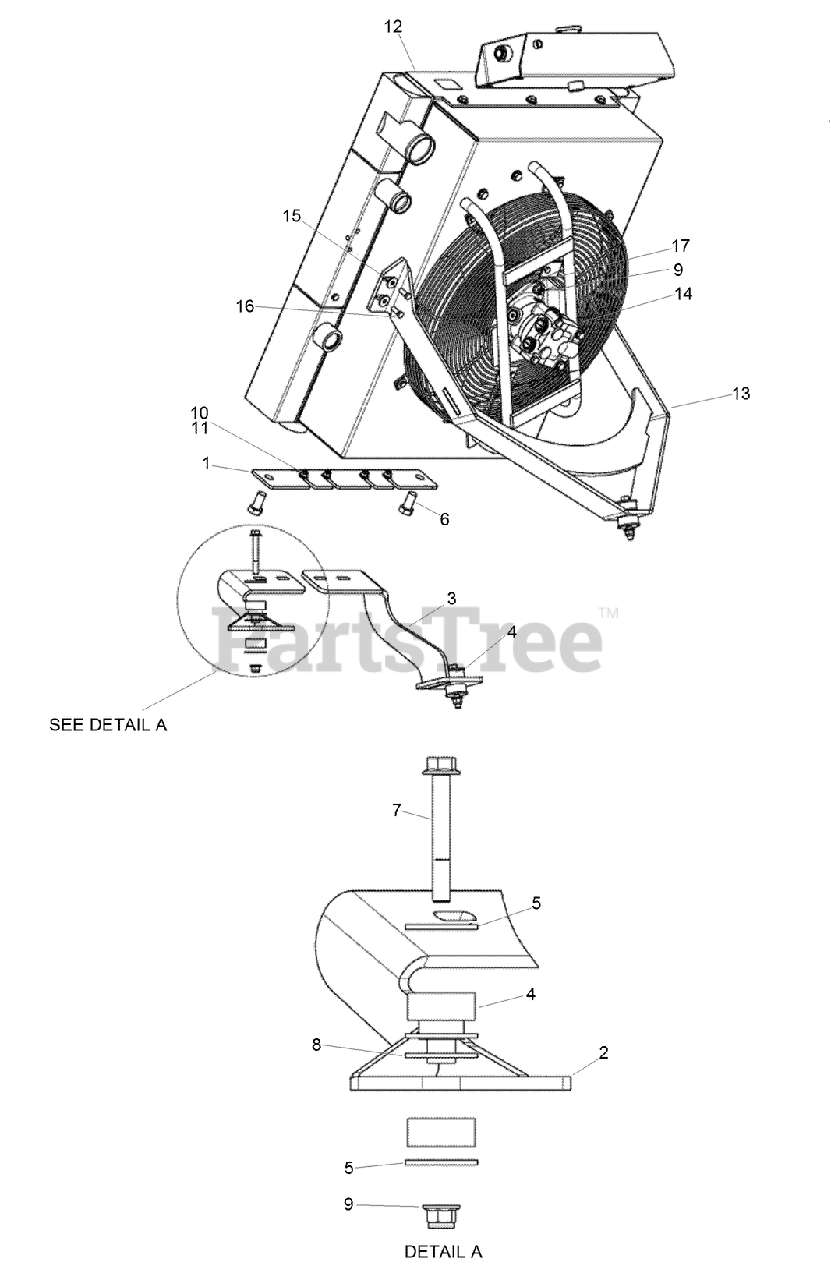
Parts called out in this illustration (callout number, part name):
1	PLATE - Mounting
2	SUPPORT - Isolator, Left
3	SUPPORT - Isolator, Right
4	ISOLATOR-MOUNTING, UNIVERSAL
5	WASHER-FLAT
7	SCREW, METRIC FLANGE w/BODY-M12 x 90
9	NUT-HHF, LOCK
10	SCREW-HHF
11	NUT-FLANGE, NYLOCK
12	PACKAGE - Cooling
13	SUPPORT - Isolator, Center
14	HYD MOTOR ASM
16	SCREW-HH
